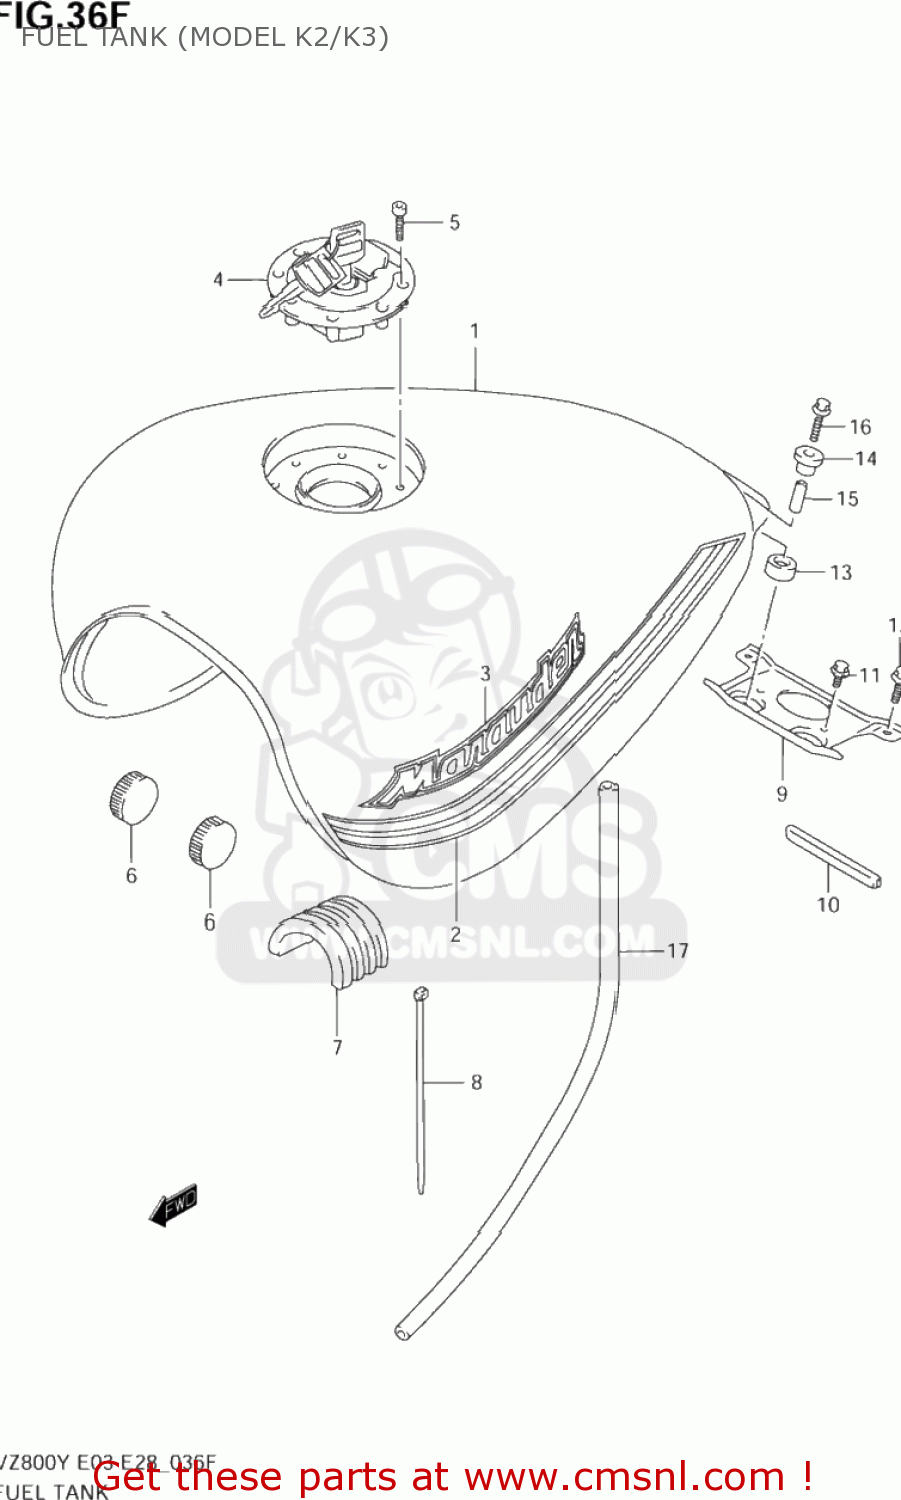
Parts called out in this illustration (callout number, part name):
1	TANK ASSY,FUEL
2	TAPE SET,FUEL TANK
3	EMBLEM,FUEL TANK
4	CAP SET,FUEL TANK
5	BOLT(5X20)
6	CUSHION
7	CUSHION,FUEL TANK UPR
8	CLAMP(L:250)
9	BRACKET,FUEL TANK RR
10	PROTECTOR
11	BOLT
12	BOLT
13	CUSHION,FUEL TANK RR NO.2
14	CUSHION
15	SPACER(6.5X10.5X22.5)
16	BOLT
17	HOSE,FUEL TANK DRAIN
